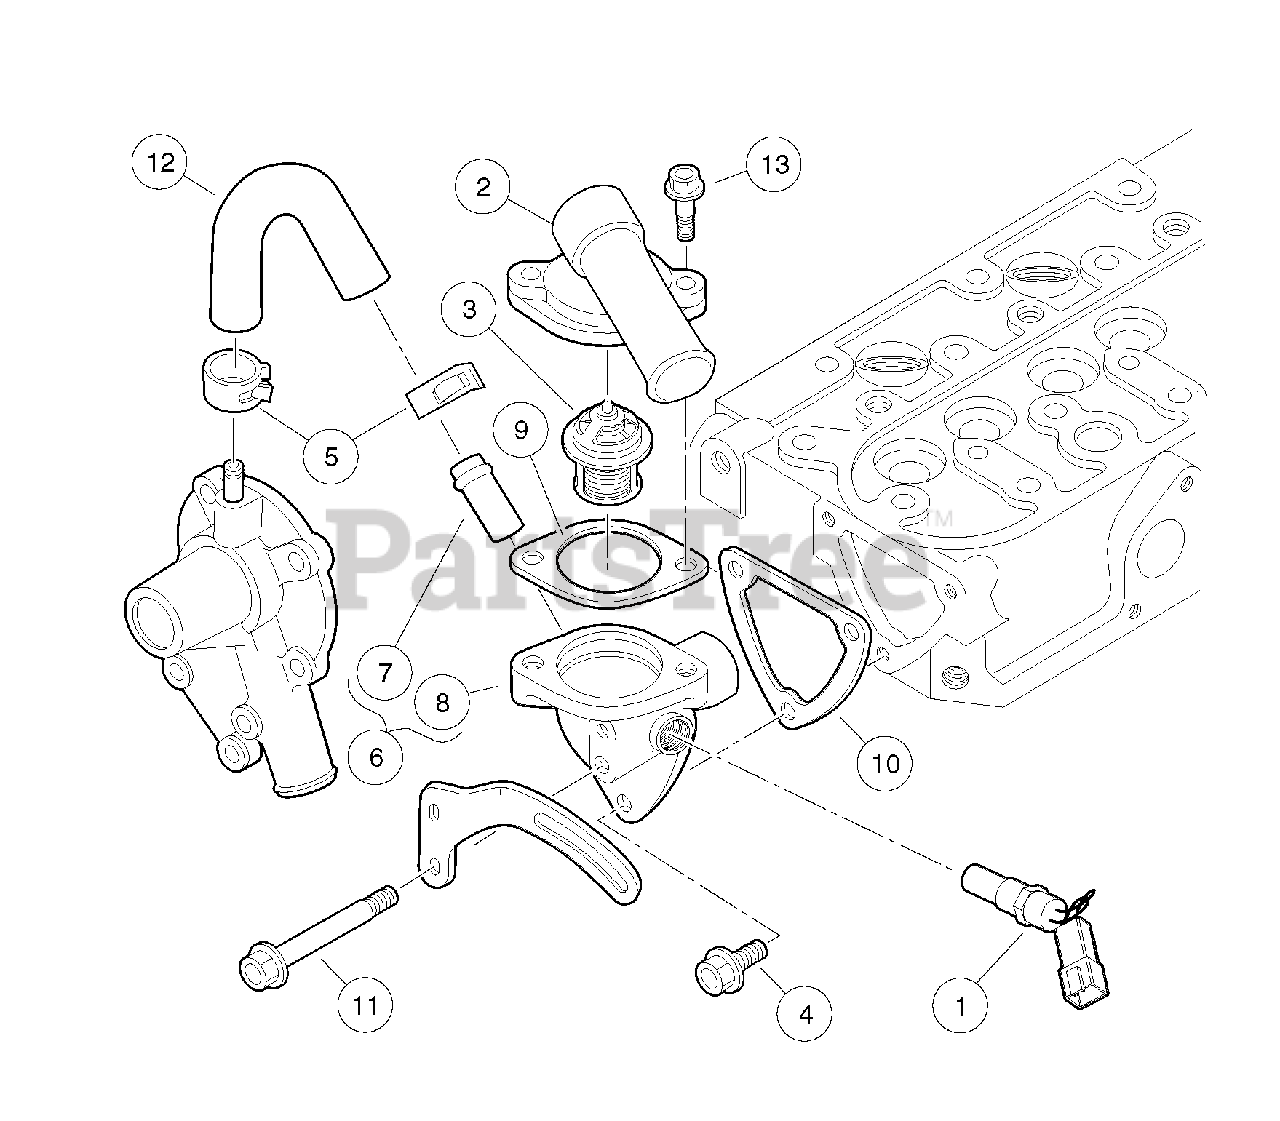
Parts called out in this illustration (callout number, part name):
1	Sensor, Coolant Temp
2	Cover, Thermostat
3	Assy, Thermostat
4	Bolt, M6 X 1 X 20
5	Band, Pipe
6	Flange, Water
7	Pipe, Water Return, D722
8	Flange, Water
9	Gasket, Thermostat
10	Gasket, Water Flange
11	Bolt, Alt, D722, Stay Lower
12	Pipe, Water Return, D722
13	Bolt, D722, Thermostat Cover
